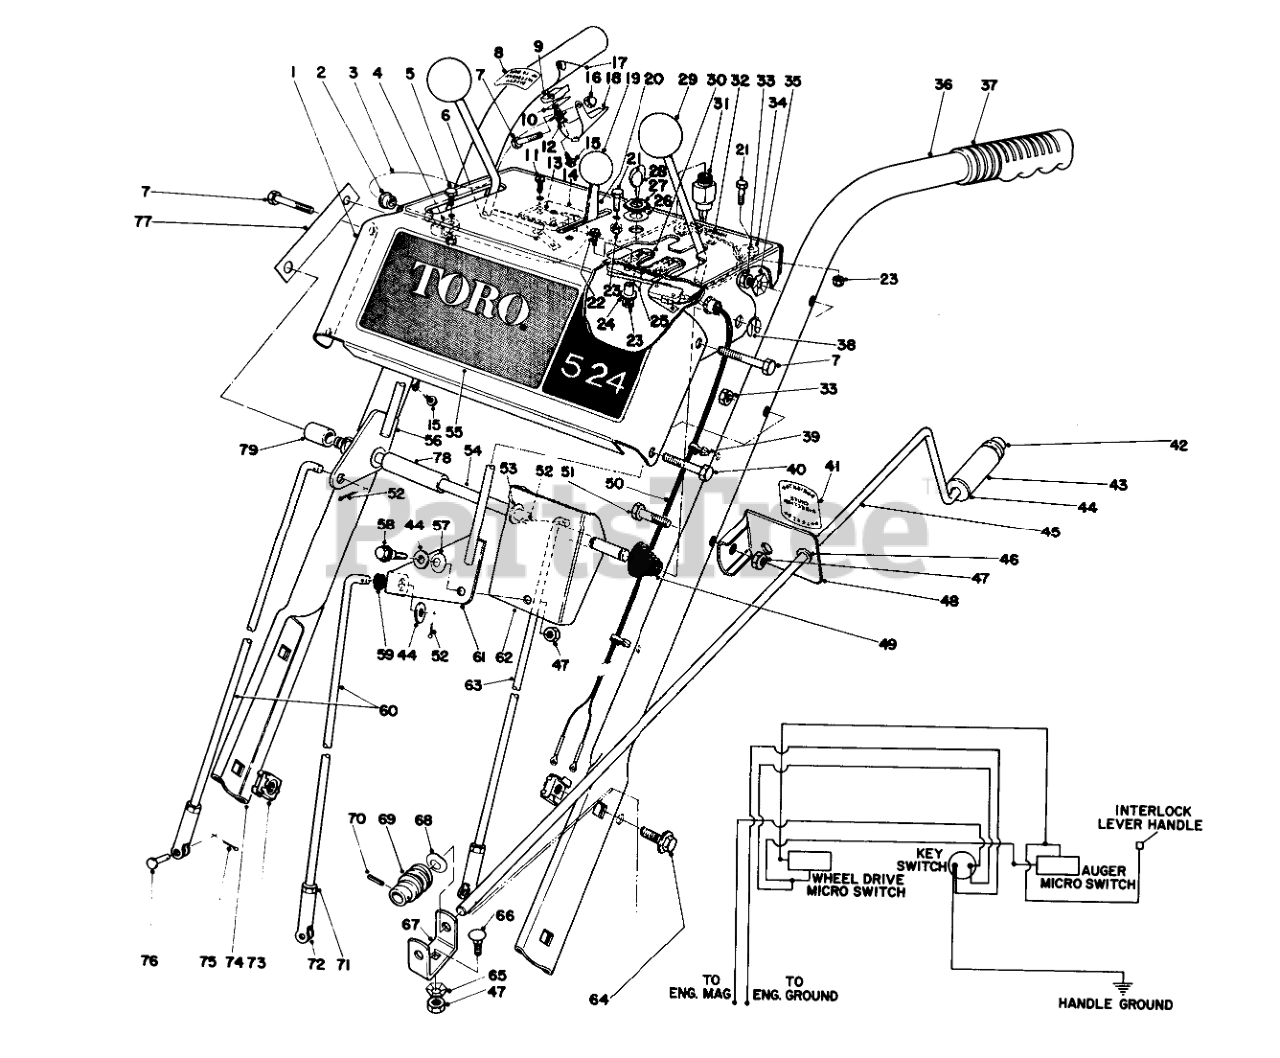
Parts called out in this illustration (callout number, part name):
1	Escutcheon
2	Snap Bushing
3	WIRE ASM
4	PLASTIC CLIP
5	SCREW-HWHTF
6	NUT-SPEED
7	SCREW-HH
8	Decal Safety Interlock
9	Insulator
10	INTERLOCK CONTACT
11	SCREW-SPH
12	WASHER INSULATOR
13	MICRO SWITCH
14	SWITCH MTG PAD
15	Screw
16	NUT-CAP
17	INTERLOCK SPRING
18	SAFETY INTRLOCK LEVER
19	CONTROL KNOB
20	Throttle Control
21	HEX HEAD SEMS 10-24X1/2
22	SCREW-SRH
23	Nut
24	INTERLOCK SPACER
25	INTERLOCK SPRING
26	WASHER-TOOTH, INTERNAL
27	NUT-HH
28	Ket (set of 2)
30	Slide Interlock
31	Switch
32	Decal Instruction
33	NUT-LOCK, CONE
34	CABLE CLAMP
35	Washer
36	LEFT HANDLE
37	Grip Handle
38	RING-CLIP
39	Mount-Wire
40	SCREW-HH
41	Decal Chute Direction
42	RETAINER-PUSH ON
43	CHUTE CONTROL GRIP
44	WASHER-FLAT
45	CHUTE CONTROL ROD
46	Bushing
47	NUT-LOCK, CONE
48	Chute Control Rod Mounting Bracket(Incl. Ref. 41 & 46)
49	CONICAL SPRING
50	Wire Harness
51	SCREW-HH
52	PIN-COTTER
53	WASHER-FLAT
54	PIVOT ROD
55	ESCUTCHEON DECAL
56	LEVER WA
57	7/16 SPRING WASHER
58	SHOULDER SCREW
59	GROMMET-RUBBER
60	SPEED SELECTOR ROD
61	SHIFT LEVER WA
62	SHIFT BRACKET
63	TRACTION CONTROL ROD
64	SCREW-HHF
65	WASHER-LOCK
66	BOLT-CARR
67	WORM BRACKET
68	WASHER-SPRING
69	GEAR-WORM, CHUTE
70	PIN-SPRING
71	NUT-HJ
72	Clevis
73	Retained Nut
74	RIGHT HANDLE
75	PIN-COTTER
76	PIN-CLEVIS
77	ESCUTCHEON SUPT STRAP
78	SHIFT LEVER SPACER
79	AUGER LEVER SPACER
